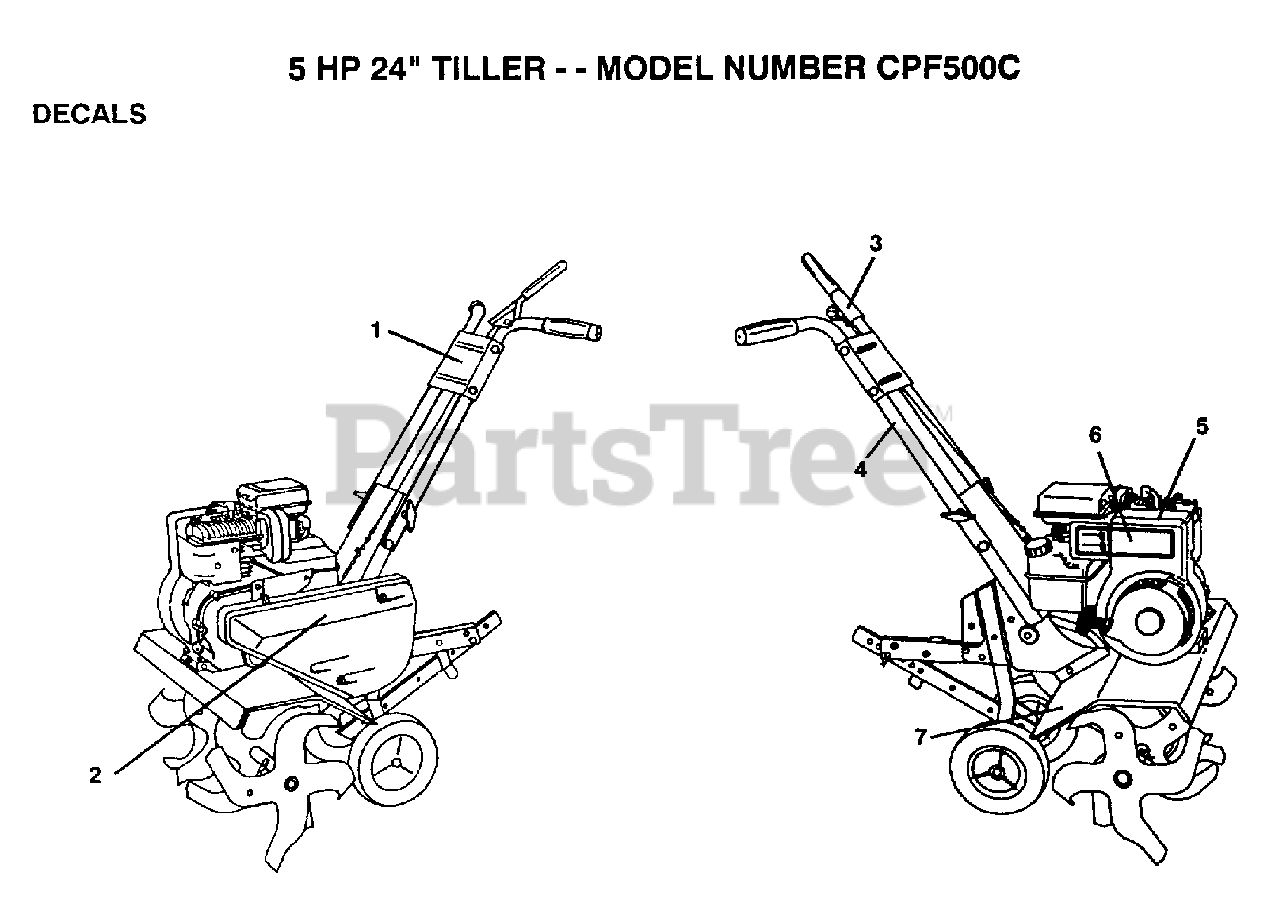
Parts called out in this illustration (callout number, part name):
3	DECAL TI
4	DECAL TI
7	DECAL TI
